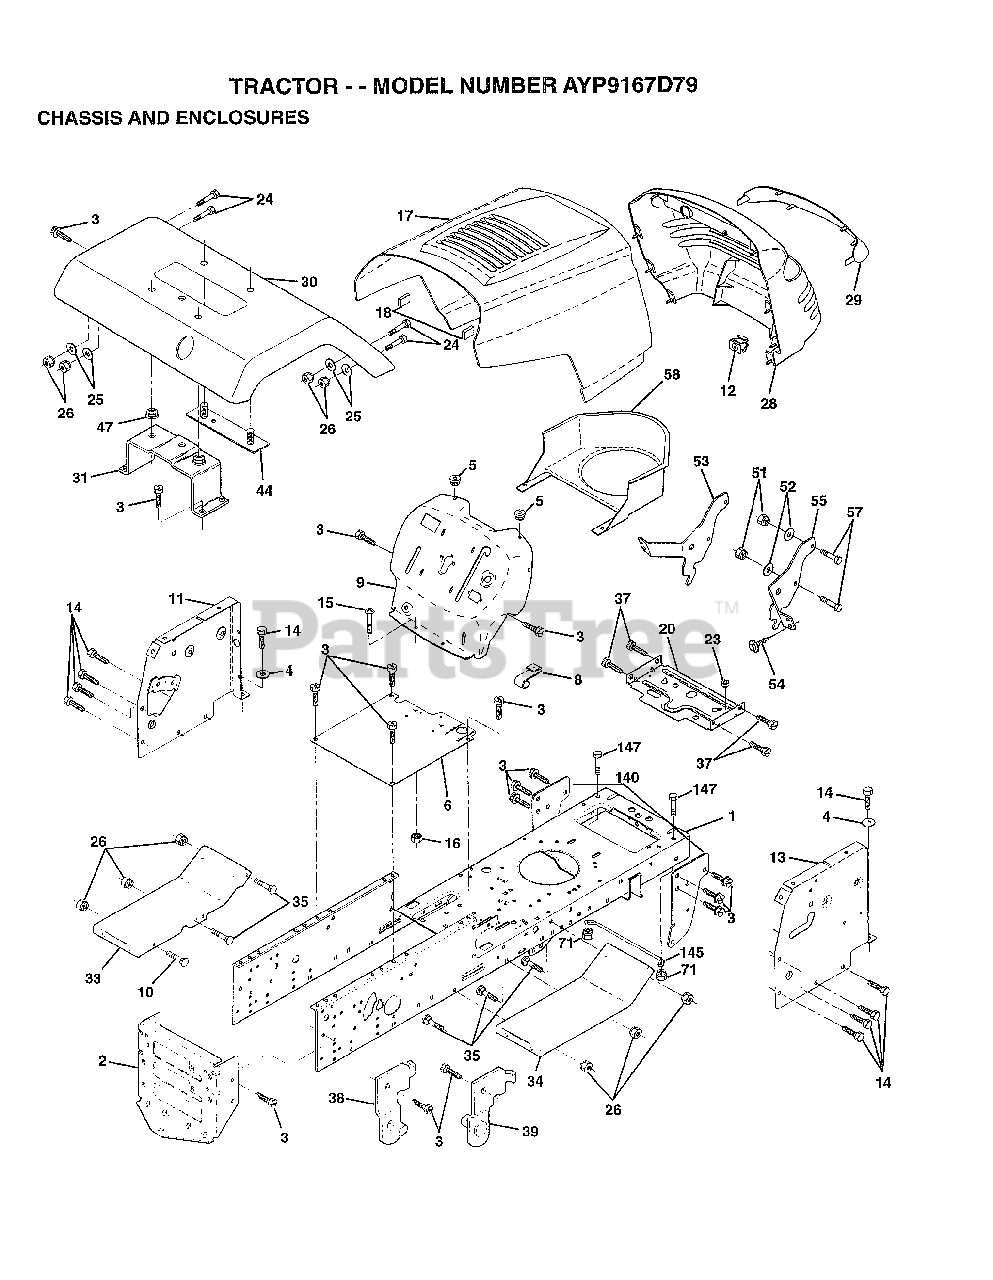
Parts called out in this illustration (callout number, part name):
1	CHASSIS ASM
3	SCREW
4	WASHER
5	BUMPER-HOOD/DASH
6	SADDLE
8	"CLIP,INSULATOR"
9	DASH SILKSCREEN
11	"PANEL-DASH,LH"
12	CLIP.TINNERMAN
13	"PANEL-DASH,RH"
14	SCREW LT
15	SCREW
17	HOOD.STEEL.ASSY
20	"PLATE-MTG,BATT/FU"
24	BOLT
25	WASHER
26	NUT
28	GRILL
29	LENS.EURO.W/DECAL
31	BRKT.ASM.FENDER
33	FOOTREST.LT.LT/GT
34	FOOTREST.RH.LT/GT
35	BOLT
37	SCREW LT
38	BRACKET ASM LH
39	BRACKET ASM RH
44	STRAP ASM FENDER
47	NUT-PUSH YT
51	NUT
52	WASHER
53	BRACKET.GRILLE.LH
55	BRACKET.GRILLE.RH
58	AIR DUCT
140	BRKT SUSPENSION
145	"ROD POVOT,CHASSIS"
147	BOLT LT
